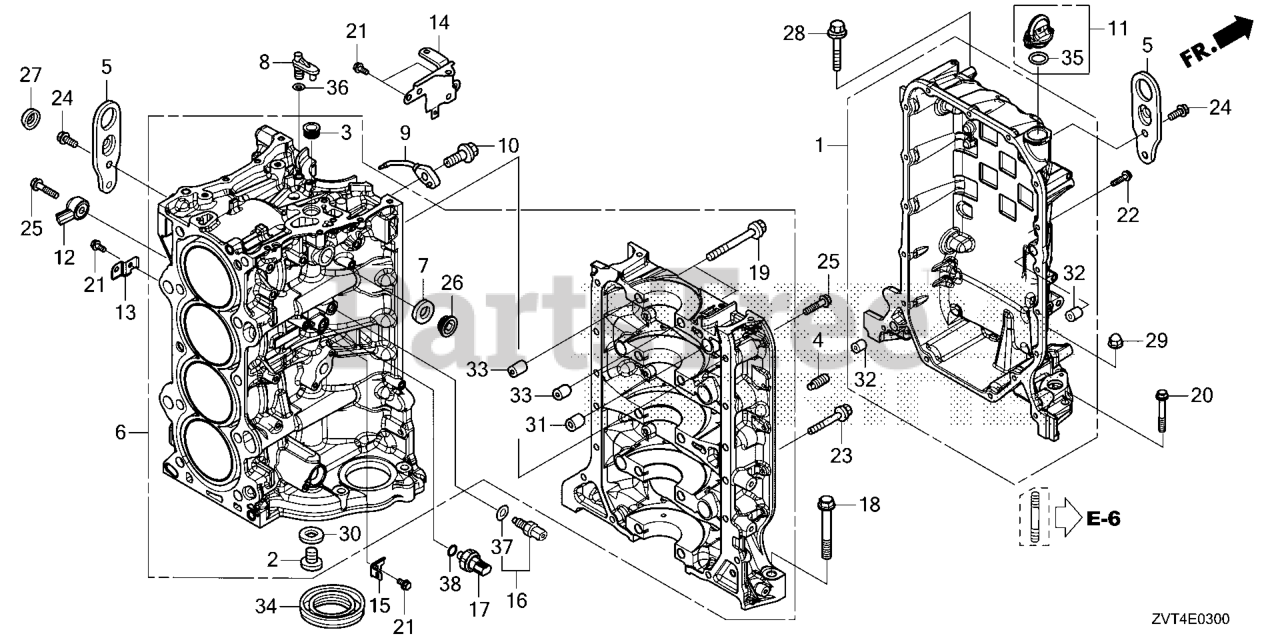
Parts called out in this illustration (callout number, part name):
1	CRANKCASE COMP
2	BOLT, SEALING (28MM)
3	BOLT, SEALING (20MM)
4	ORIFICE, BLOCK (LOWER)
5	HANGER, ENGINE
6	BLOCK (0000) *NH8*
7	WASHER, SEALING (22MM)
8	ORIFICE, OIL JET
9	BODY, OIL JET
10	BOLT, OIL JET
11	CAP ASSY., OIL FILLER
12	SENSOR, KNOCK
13	BRACKET, CLIP B
14	BRACKET D, HARNESS CLIP
15	BRACKET, HARN CLIP G
16	SENSOR ASSY., WATER TEMPERATURE
17	SENSOR, OIL PRESSURE
18	BOLT, FLANGE (12X83)
19	BOLT-WASHER (11X95)
20	BOLT, FLANGE (8X55)
21	BOLT, FLANGE (6X14) (CT200)
22	BOLT, FLANGE (6X25)
23	BOLT, FLANGE (8X50)
24	BOLT, FLANGE (8X20)
25	BOLT, FLANGE (8X35)
26	BOLT, SEALING (22MM)
27	CAP, BOLT (8MM)
28	BOLT, FLANGE (10X70)
29	NUT (10MM)
30	WASHER, SEALING (28MM)
31	PIN, DOWEL (18X22)
32	PIN, DOWEL (13X20)
33	PIN, DOWEL (13X14)
34	OIL SEAL (80X98X10) (ARAI)
35	O-RING (18.1X3.6)
36	O-RING (6.5X1.5)
37	O-RING (9.5X1.9)
38	O-RING (13X1.5) (ARAI)
